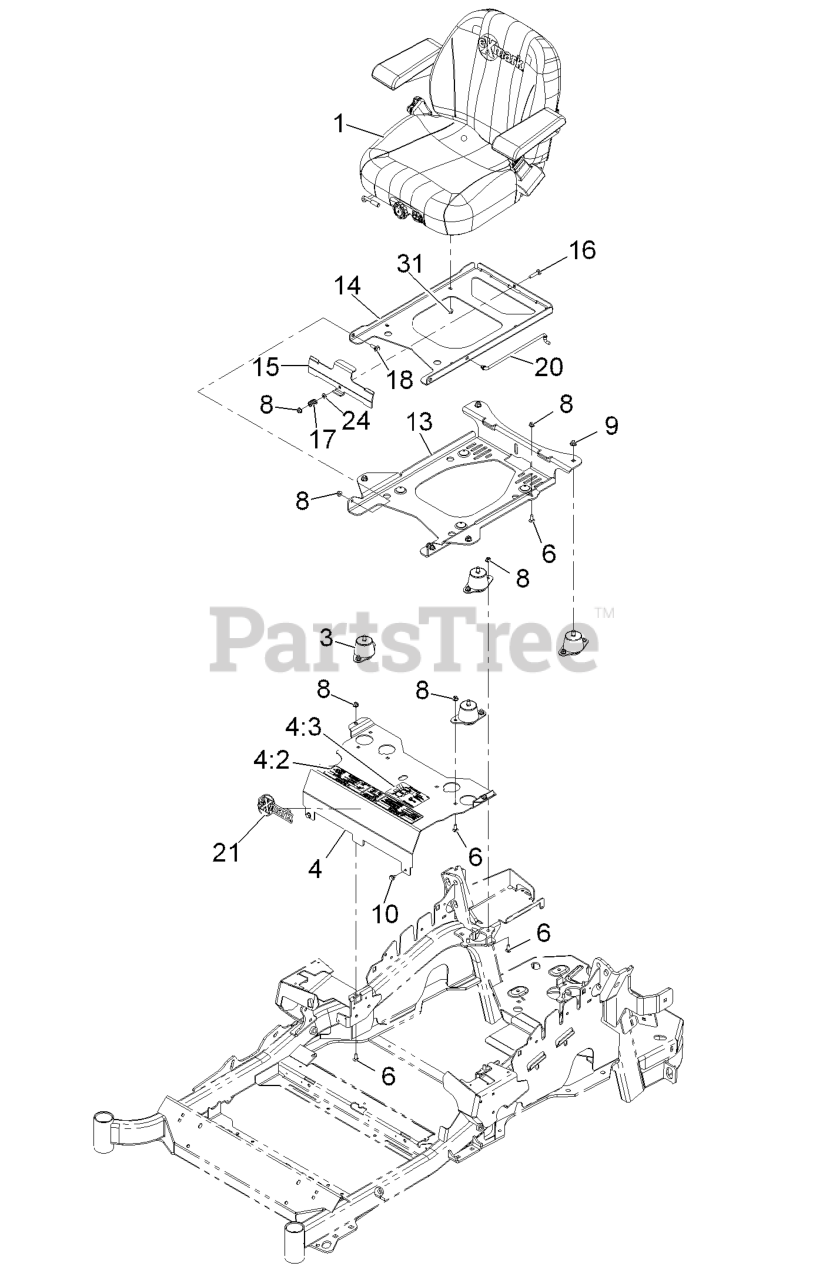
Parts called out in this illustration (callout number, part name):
3	ISOLATOR-SEAT
4	MOUNT-SEAT
4:2	DECAL-CONSOLE
4:3	DECAL-SERVICE AID
6	SCREW-CARR
8	NUT-HF, NI
9	NUT-HF, NI
13	PLATE-SUPPORT, SEAT TILT
14	PLATE-FRAME, SEAT TILT
15	PLATE-LATCH, SEAT
16	BOLT-CARR
17	SPRING-COMPRESSION
18	SCREW-SHOULDER
20	ROD-PROP
24	WASHER-PLAIN
